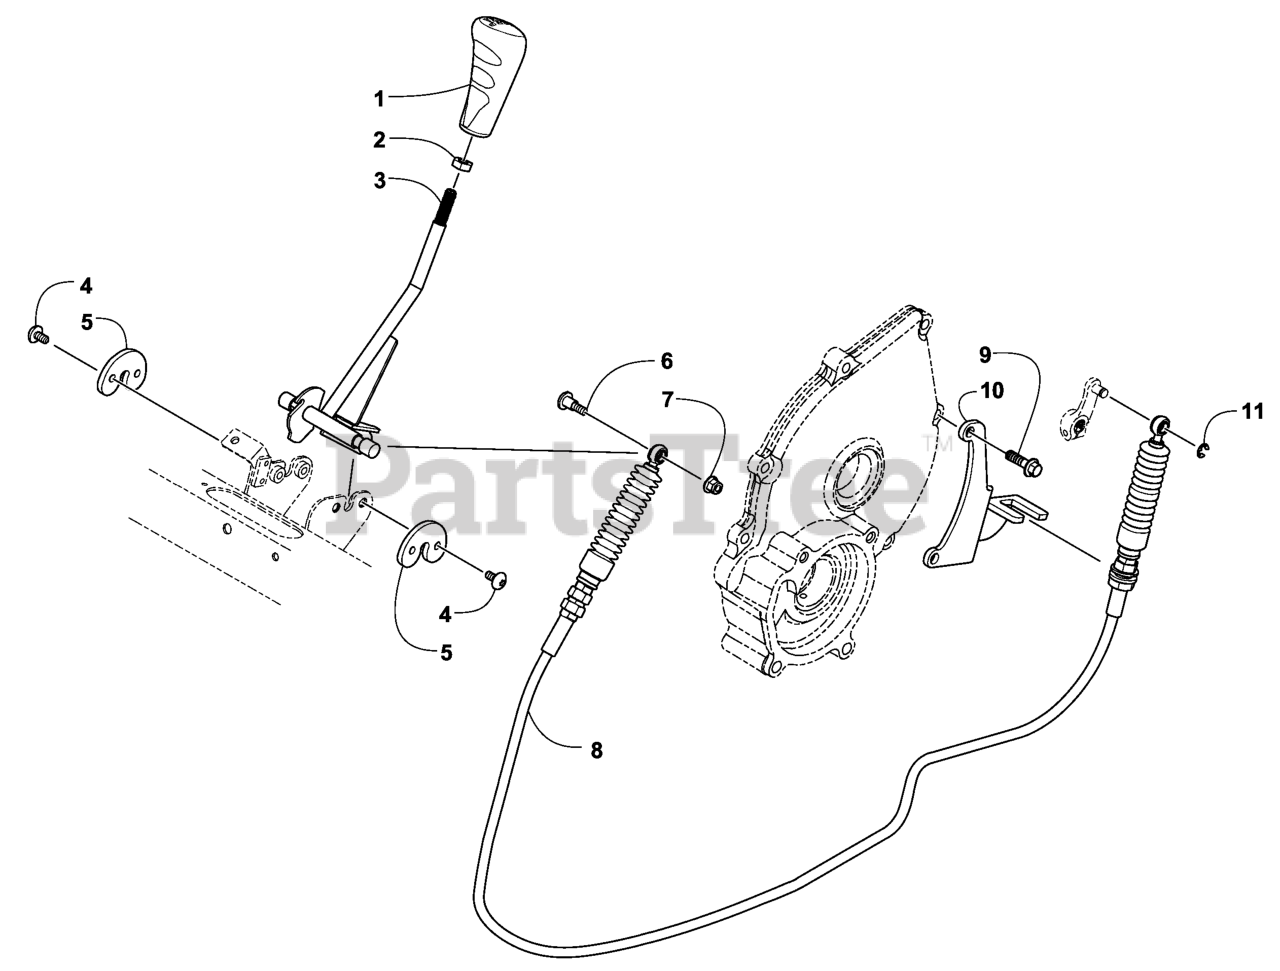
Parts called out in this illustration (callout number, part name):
1	KNOB-SHIFT
2	NUT-JAM
3	AXLE-SHIFT(DASH)
4	SCREW-TSPH
5	RETAINER-SHIFT LINKAGE
6	SCREW-SHOULDER
7	LINKAGE,LOWER CALIPER RH
9	BOLT-FLANGE
10	BRACKET-SHIFT CABLE
